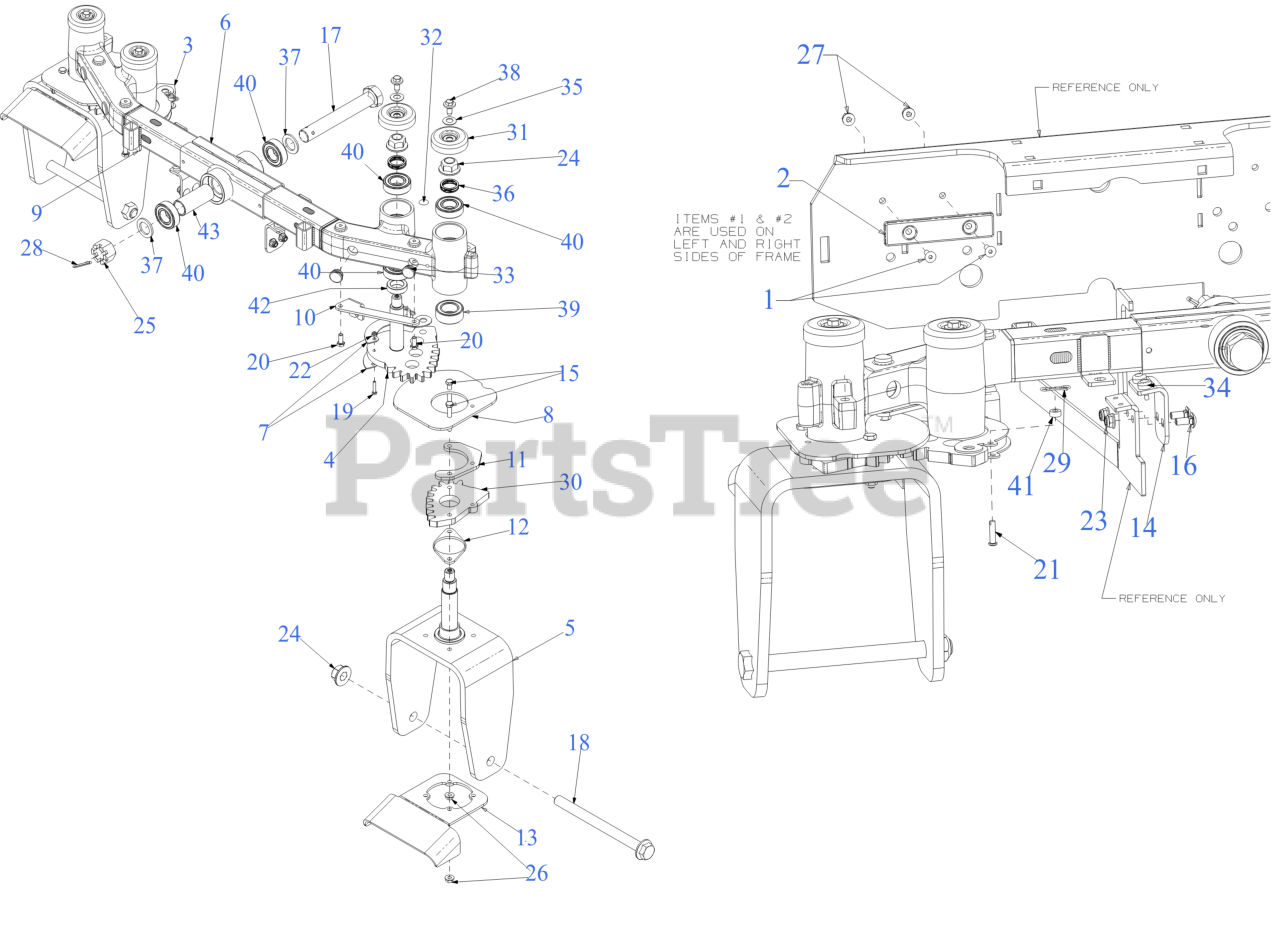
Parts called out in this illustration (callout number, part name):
1	SCREW-FLAT HEAD CA
2	PLATE-LIFT WEAR
3	LEFT HAND STEERING GEAR ASSEMBLY
4	RIGHT HAND STEERING GEAR ASSEMBLY
5	YOKE ASSEMBLY
5	YOKE REPLACEMENT KIT (FRONT)
6	AXLE ASSEMBLY
7	CABLE BEAR MOUNTING BRACKET
12	LOWER GEAR SPACER PLATE
14	AXLE BRACKET
15	HEX SCREW 5/16-18 x 2.25 GR5
16	CARRIAGE BOLT 5/16-18 x .75
17	HEX HEAD SCREW (1-14 x 7 GR5)
18	SCREW 3/4-16 x 9.00 GR5
19	SCREW #10-24 x 1.00 GR5.1
20	SCREW 5/16-18 x .750
21	CLEVIS PIN .25 x 1.00
23	FLANGE LOCK NUT 5/16-18
24	FLANGE LOCK NUT 3/4-16 TOP LOCK
25	CASTLE NUT 1.0-14 GR5
26	HEX FLANGE NUT
27	LOCK NUT 1/4
28	COTTER PIN
29	BOW TIE COTTER PIN 1/4-5/16
30	STEERING GEAR YOKE
31	AXLE CAP 2.5"
32	RATCHET CLIP
34	BUMPER, .62 DIA x .3
35	BELL WASHER
36	WAVE WASHER
37	FLAT WASHER 1.005 x 1.570 x 0.125
39	BALL BEARING 30x52x20
40	BALL BEARING (1.0 x 52 x 15)
43	SPACER 1.00 x 1.25 x 2.99
